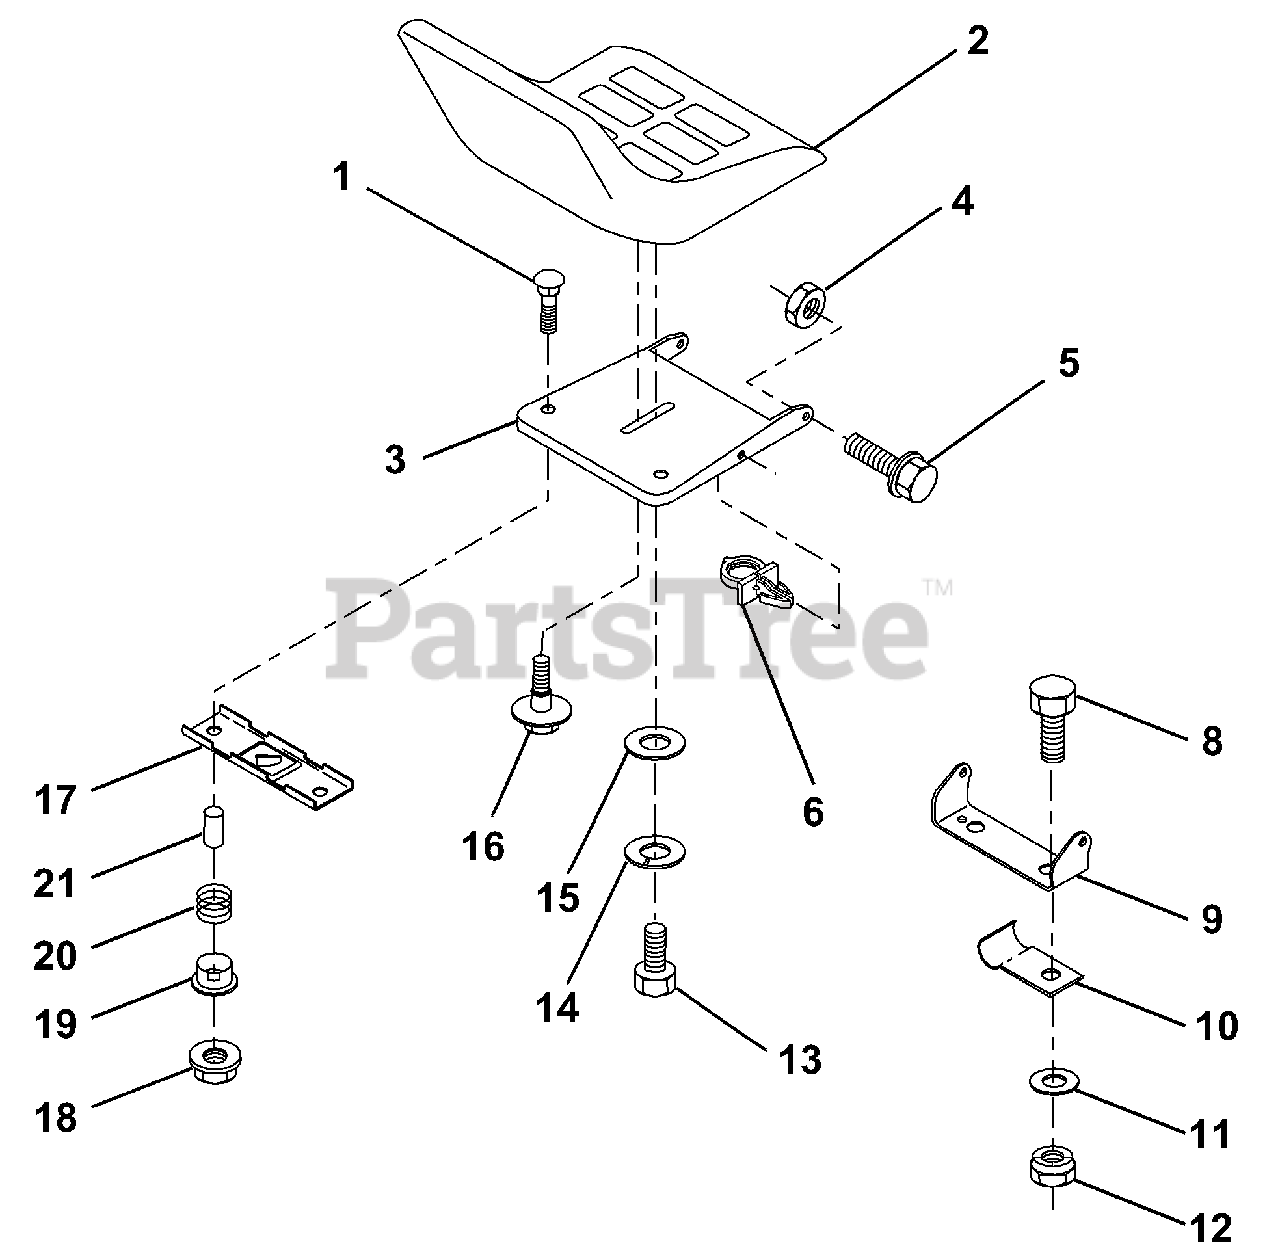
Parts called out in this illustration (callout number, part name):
1	Bolt, Carriage 1/4-20 x 1-3/8
2	Seat
3	Pan, Sea
4	Locknut, Hex w/Ins 5/16-18
5	Bolt, Shoulder 5/16-18 UNC
6	Clip, Push-in
8	Bolt, Fin Hex 3/8-16 UNC x 1
9	Bracket, Pivot Seat
10	Clip, Insulated
11	Washer 12/32 x 2 x 10 Ga.
12	Nut, Lock Hex w/Wsh 3/8-16
13	Bolt Hex 1/2-13 x 7/8
14	Washer Lock Hvy. Hlicl Spring 1/2
15	Washer, 17/32 x 1-3/16 x 12 Ga.
16	Bolt, Shoulder
17	Bracket, Switch, Mounting
18	Nut, Hex Large Flange Lock
19	Bushing, Snap
20	Spring, Compression
21	Spacer, Split 28 Id. x .88 Lg.
